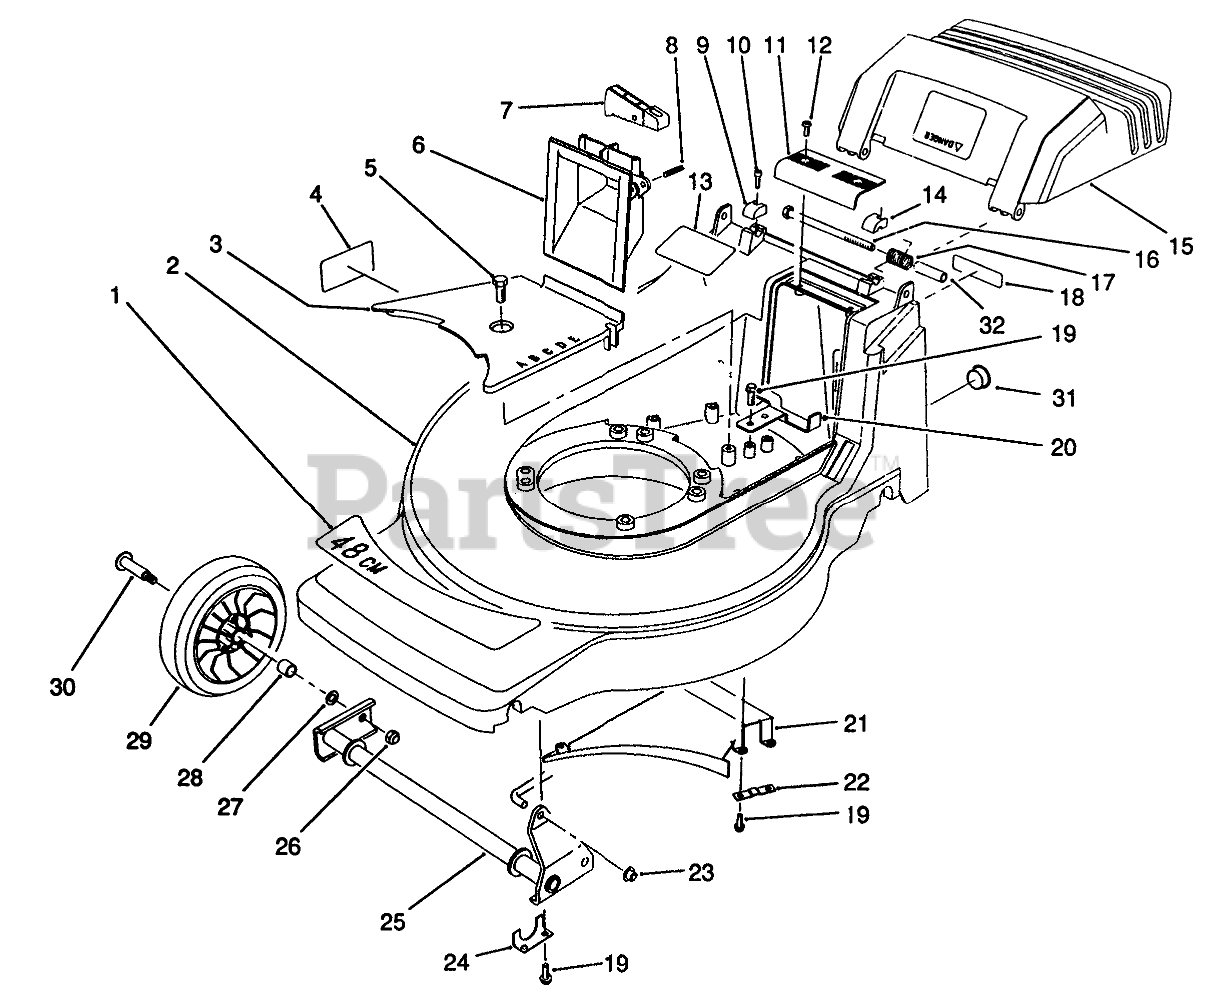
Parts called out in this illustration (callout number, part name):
1	DECAL - DECK
2	Housing-48cm
3	BELT COVER
4	Decal Danger
5	SCREW-HWHTF
6	GRIP - LOWER
7	TRIGGER - HOC
8	PIN-SPIRAL
9	CAP-HINGE BOLT, RH
10	SCREW-HSH
11	GRIP-UPPER
12	SCREW-PPH, PLASTITE
13	Decal-Noise
14	CAP-HINGE BOLT, LH
15	Door-Discharge
16	SCREW-HH
17	DOOR SPRING
18	DECAL FRENCH REGUL.
19	SCREW-HWHTF
20	REAR BELT GUIDE
21	Ramp-Discharge
22	Strap-Rear Suspension
23	NUT-PUSH
24	FRONT SECURING PLATE
25	FRONT PIVOT WA
26	Nut
27	WASHER
28	BUSHING
29	Wheel & Tire Assembly (Incl. Ref. #28)
30	BOLT-WHEEL
31	DOME PLUG (DP-1000)
32	SPACER-DOOR
